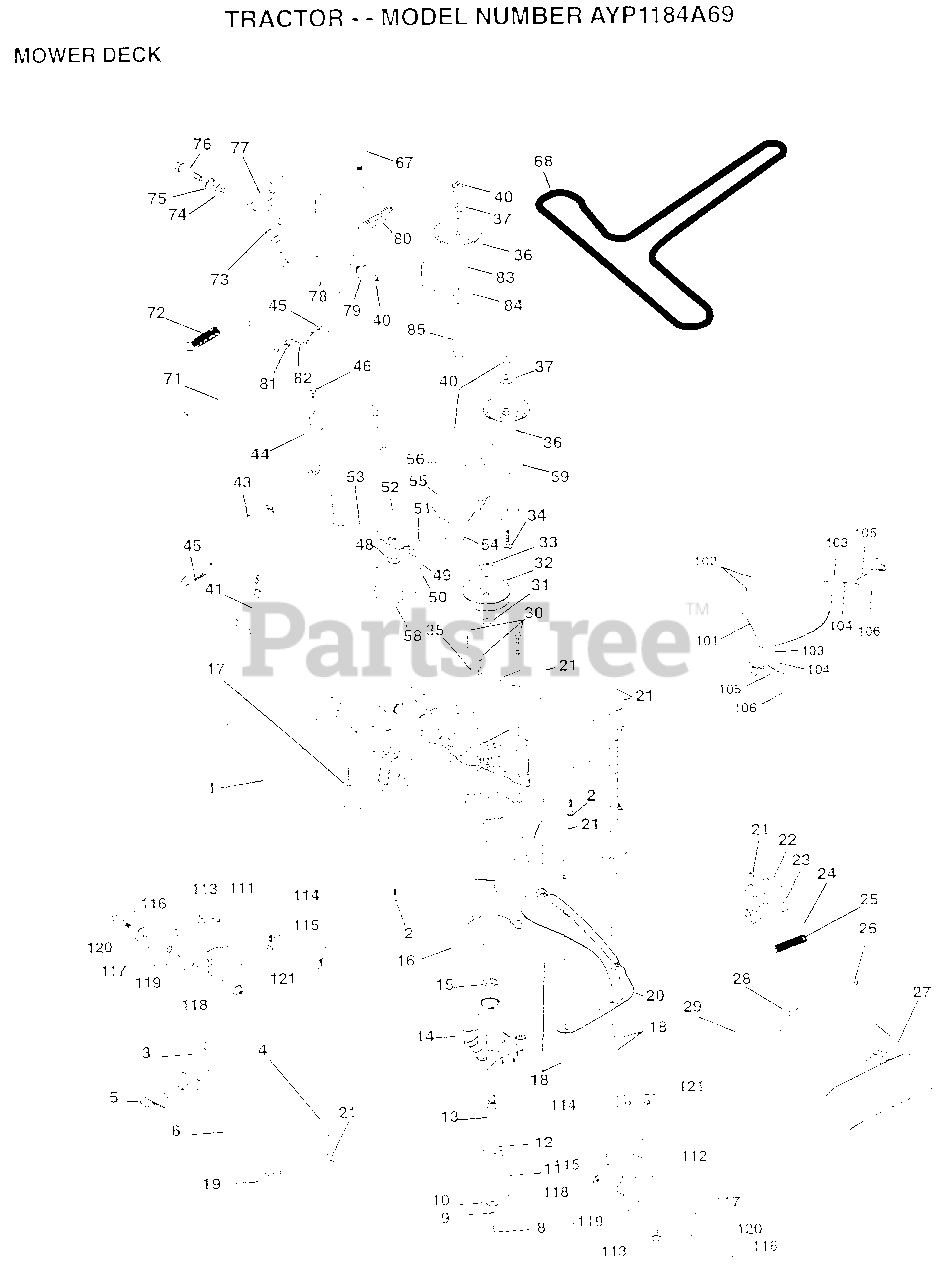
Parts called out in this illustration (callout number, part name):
1	DECK.WELD.42.
2	BOLT
3	BRKT ASM SWAY BAR
4	BRKT DECK SW BAR
8	BLADE BOLT
10	WASHER.HARD.BLADE
11	"BLADE.42"" MULCHER"
12	BEARING.BALL
14	HSG ASM MANDREL
15	BEARING
16	STRIPPER RND MWR
17	BOLT RDHD 3/8-16
18	BOLT
19	BOLT SHD 5/16-18
22	STIFFENER BRKT
23	DEFLECTOR BRKT
24	CAP-SLEEVE LT
25	SPRING TORSION
26	NUT PUSH M
27	DEFLECTOR.SHIELD
28	WASHER
29	HINGE ROD
31	WASHER
34	BOLT
35	XMAS TREE FASTNER
36	FLAT IDLER PULLEY
37	WASHER
41	PIVOT ROD
43	ROD CLUTCH W/NIBS
44	GUARD MAND LH BLK
45	RETAINER M
46	SCREW.1/4-20X5/8
48	HARD SMALL WASHER
50	SHOULDER BOLT
51	LOCKNUT
52	BOLT.SHLD.5/16-18
53	BRAKE PAD ARM ASM
54	HARDENED WASHER
56	SPACER RETAINER
58	SPRING TORSN BRAK
59	GUARD IDLER TUV
67	KNOB T (1/2-HOLE)
68	BELT.V.T-PATH
71	ROD CLUTCH 38/42
72	RETURN SPRING
73	CLUTCH ARM SECOND
74	WASHER
75	RING
76	SHOULDER BOLT
77	SPRING KEEPER
78	LEVER ASM CLT PRM
79	BUSHING
81	NUT
82	TRUNION ADJ
83	WASHER
85	BOLT RDHD 3/8-16
101	"COVER.MULCH.42"""
102	SCREW
103	WASHER #10
104	LOCKWASHER
106	WELDNUT
113	SCREW
116	BOLT M
117	WHEEL.GAGE.BLK.PL
118	LOCKNUT
119	WASHER
121	BRACKET.EXTRD.GWL
